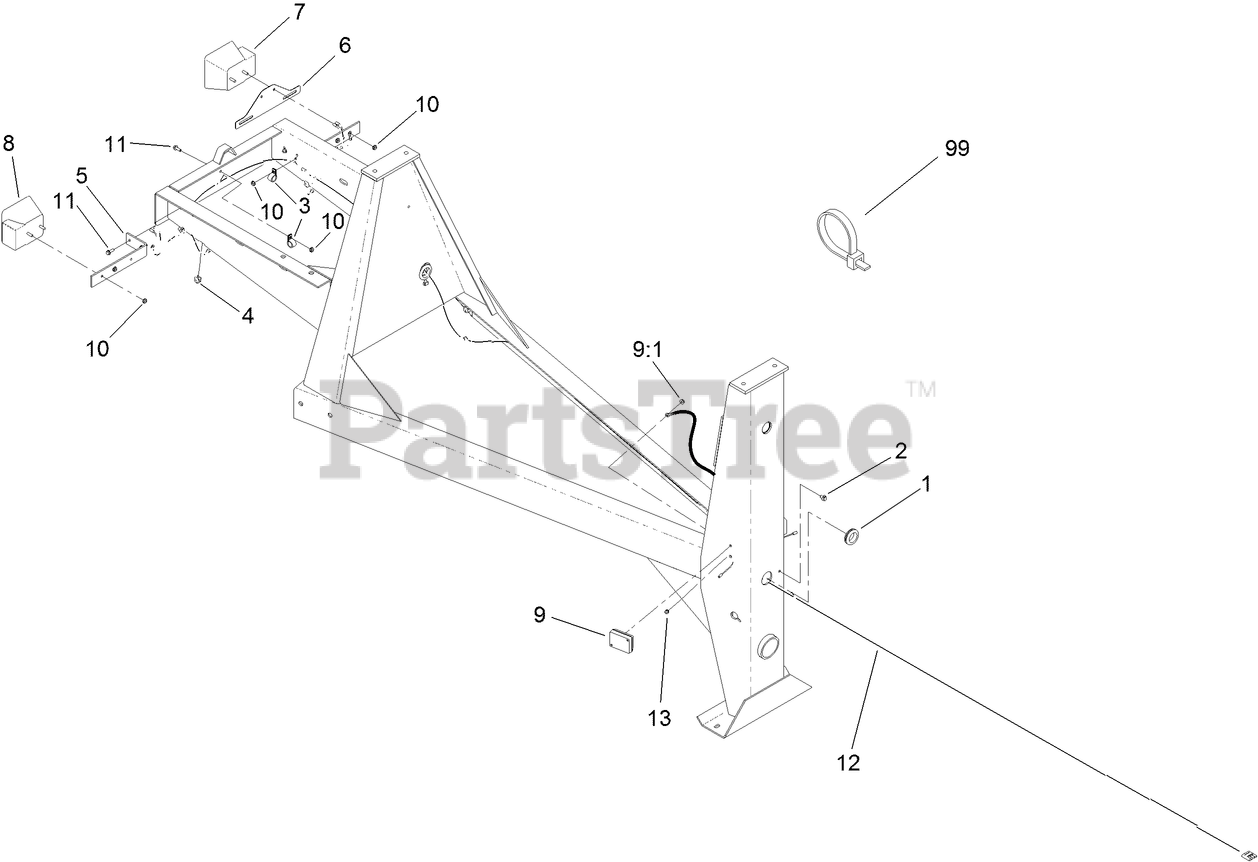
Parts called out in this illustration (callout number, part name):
1	GROMMET
2	CLIP-TIE
3	CLAMP-CABLE
4	CLIP-EDGE
5	BRACKET-UNIVERSAL
6	HOLDER-PLATE, LICENSE
7	LIGHT-TAIL, LH
8	LIGHT-TAIL, RH
9	LAMP-MARKER, FRONT SIDE
9:1	NUT-KEPS
10	NUT-KEPS
11	SCREW-HHF
12	HARNESS-WIRE
13	GROMMET
99	TIE-CABLE
